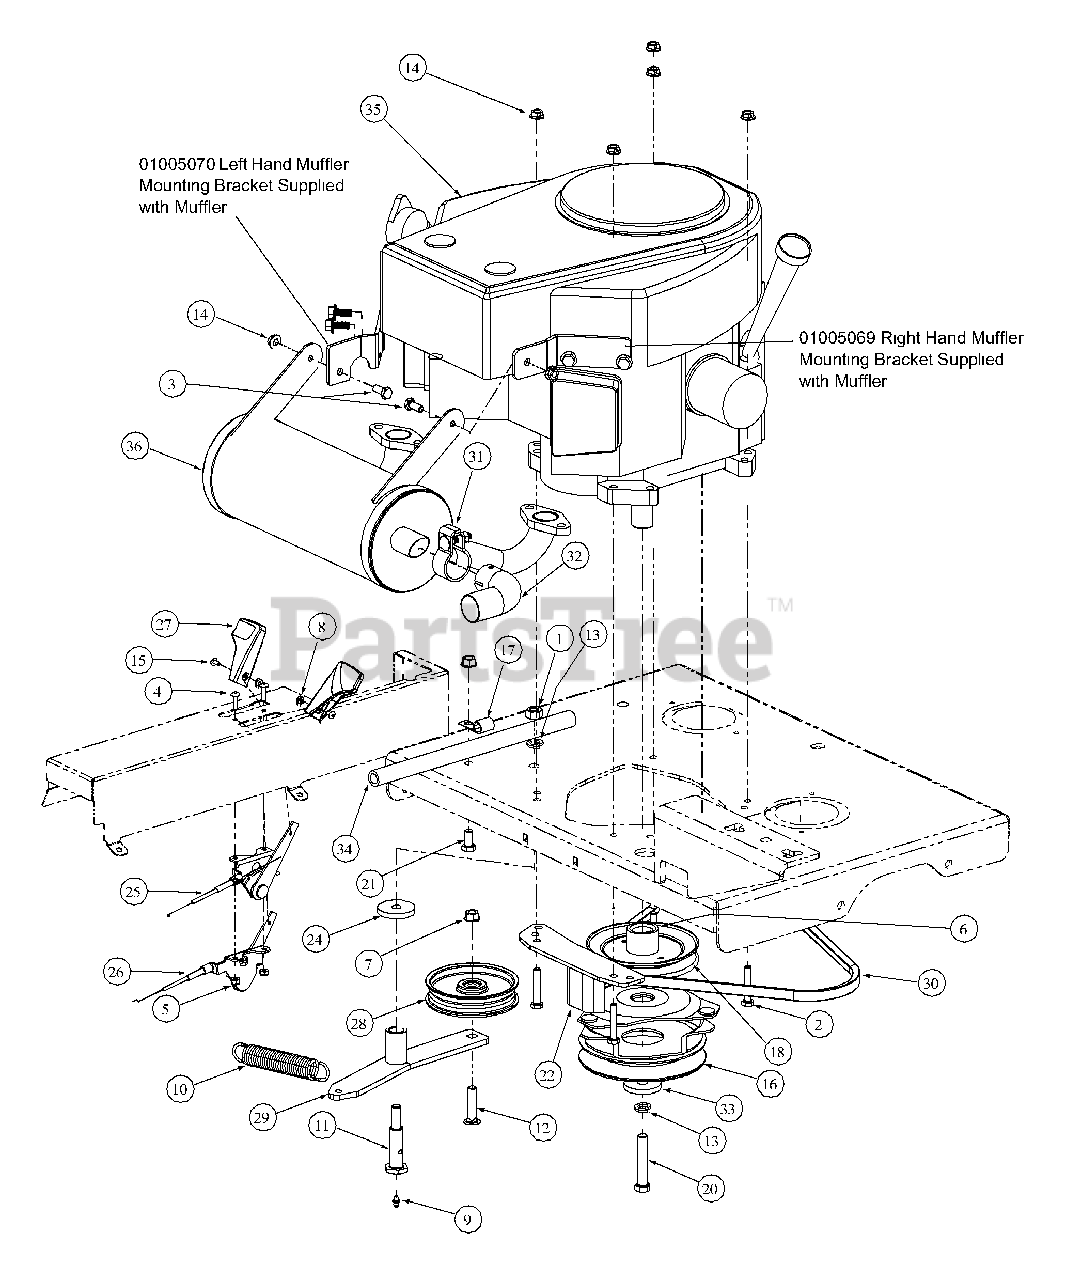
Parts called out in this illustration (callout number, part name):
1	Hex Nut, 7/16-14
2	HHCS, 5/16-18, 1-3/4
3	Hex Cap Screw, 5/16-18 x 3/4
4	Round Hd. Machine Screw, 10-32 x 3/4
5	Lock Nut, Nylon Insert, 10-32
6	Key, 1/4 x 1/4 x 1-1/8
7	Flange Lock, Hex Nut, 3/8-16
8	Nut Washer, W/Star, 8-32
9	Grease Fitting, 1/4-28 x 3/16
10	Extension Spring, 1.0 OD x 5.125
11	Shoulder Screw, 7/16-14
12	Hex Carriage Screw, 3/8-16, 1.75
13	Lock Washer, 7/16
14	Hexflange Lock Nut, 5/16-18
15	Machine Screw, 8-32, .375
16	Electric Clutch
17	Clip, Heat Shield Cable
18	Transmission Drive Pulley
20	Capscrew, 7/16-20 x 2.50
21	Hex Cap Screw, 3/8-16, .750
22	Retainer Clutch Assembly, Ogura
24	Flat Washer, 7/16 ID x 1.75 OD x .25
25	Choke, Control Cable, 43.0
26	Throttle, Control Cable, 39.0
27	Control Throttle Knob
28	Flat Pulley with Flanges
29	Engine Idler Arm Assembly
30	V Belt, A Section x .47.3
31	Tube Clamp, 1.375
32	Muffler Accessory Exhaust Tube
33	Flat Washer, 7/16 IDx 1.750 OD x
34	Oil Drain Hose
35	17HP Kawasaki Engine
36	17HP Kawasaki Exhaust
